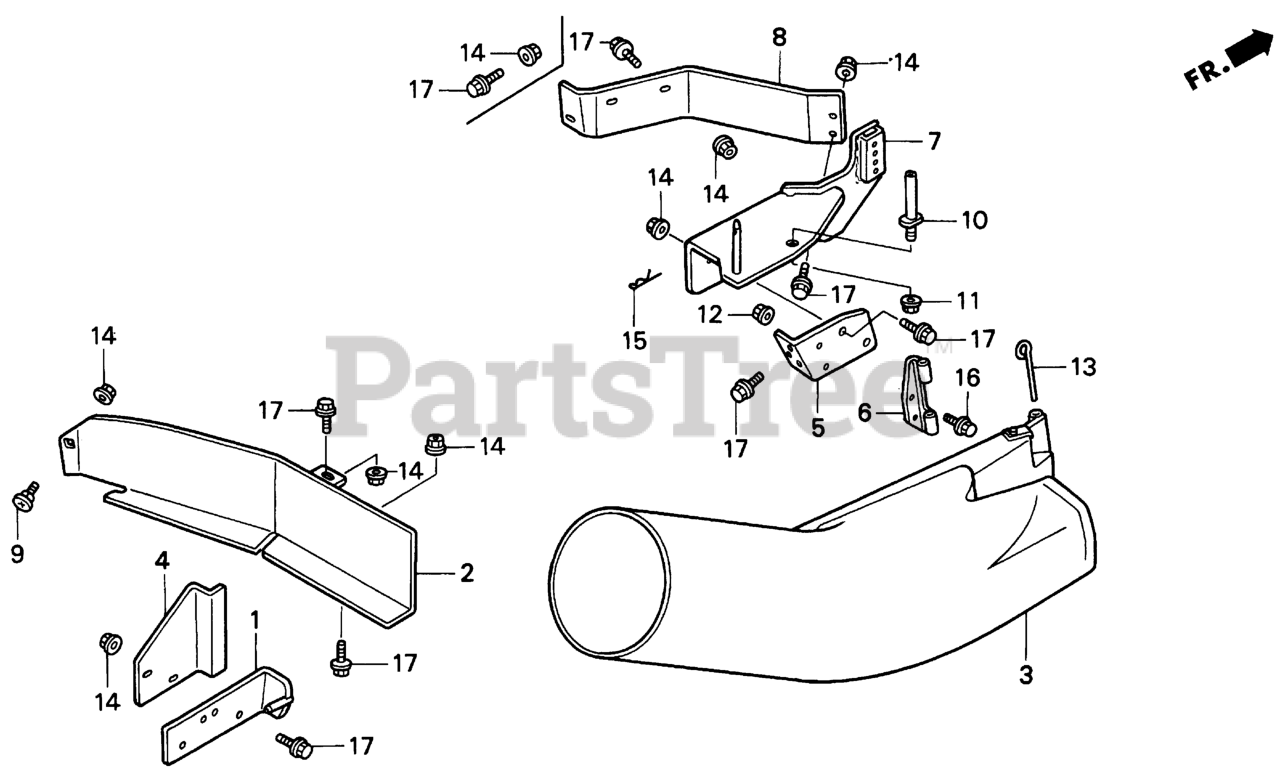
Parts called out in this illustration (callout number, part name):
1	BRACKET, R. RR. ANTI-SCALP ROLLER
2	PLATE, LAWN GUIDE
3	CHUTE (LOWER)
4	PLATE, CHUTE SEAL
5	BRACKET, SIDE BLOWER
6	HOLDER, PIN
7	STAY, SIDE BLOWER
8	PLATE, BASE
9	BOLT, SPECIAL (8X20)
10	SHAFT, ANTI-SCALP ROLLER
11	NUT, SELF-LOCK (12MM) (SATO RASHI)
12	NUT, FLANGE (6MM)
13	PIN, CHUTE (LOWER)
14	NUT, FLANGE (8MM)
15	PIN, LOCK (10MM) Use from Frame SN 2149606 to 2149605.
16	BOLT, FLANGE (6X18)
17	BOLT, FLANGE (8X20)
